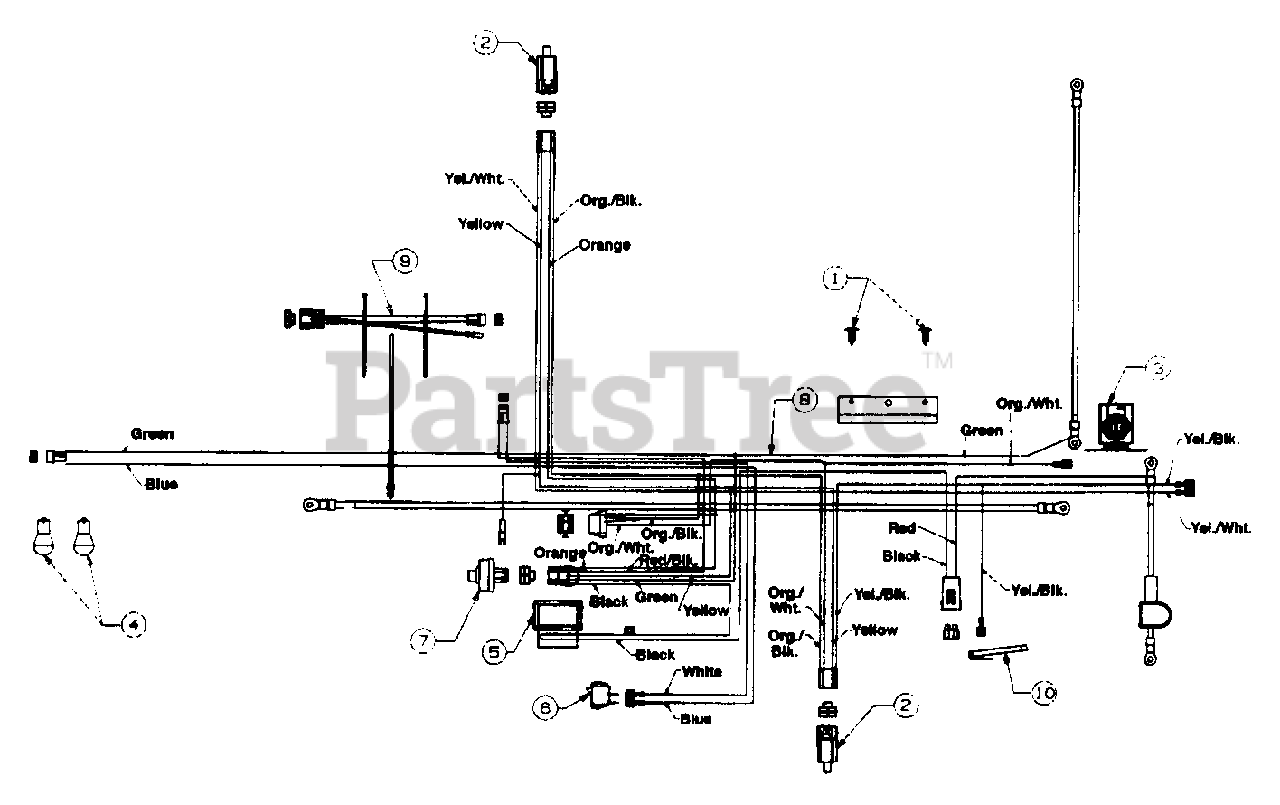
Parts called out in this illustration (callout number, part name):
1	Ratchet
2	Safety Switch
3	Solenoid
4	Bulb (Headlight)
5	Ammeter
6	Light Switch
7	Ignition Switch
8	Wire Harness
9	Wire Harness Adapter
10	Wire Harness (Monitor)
